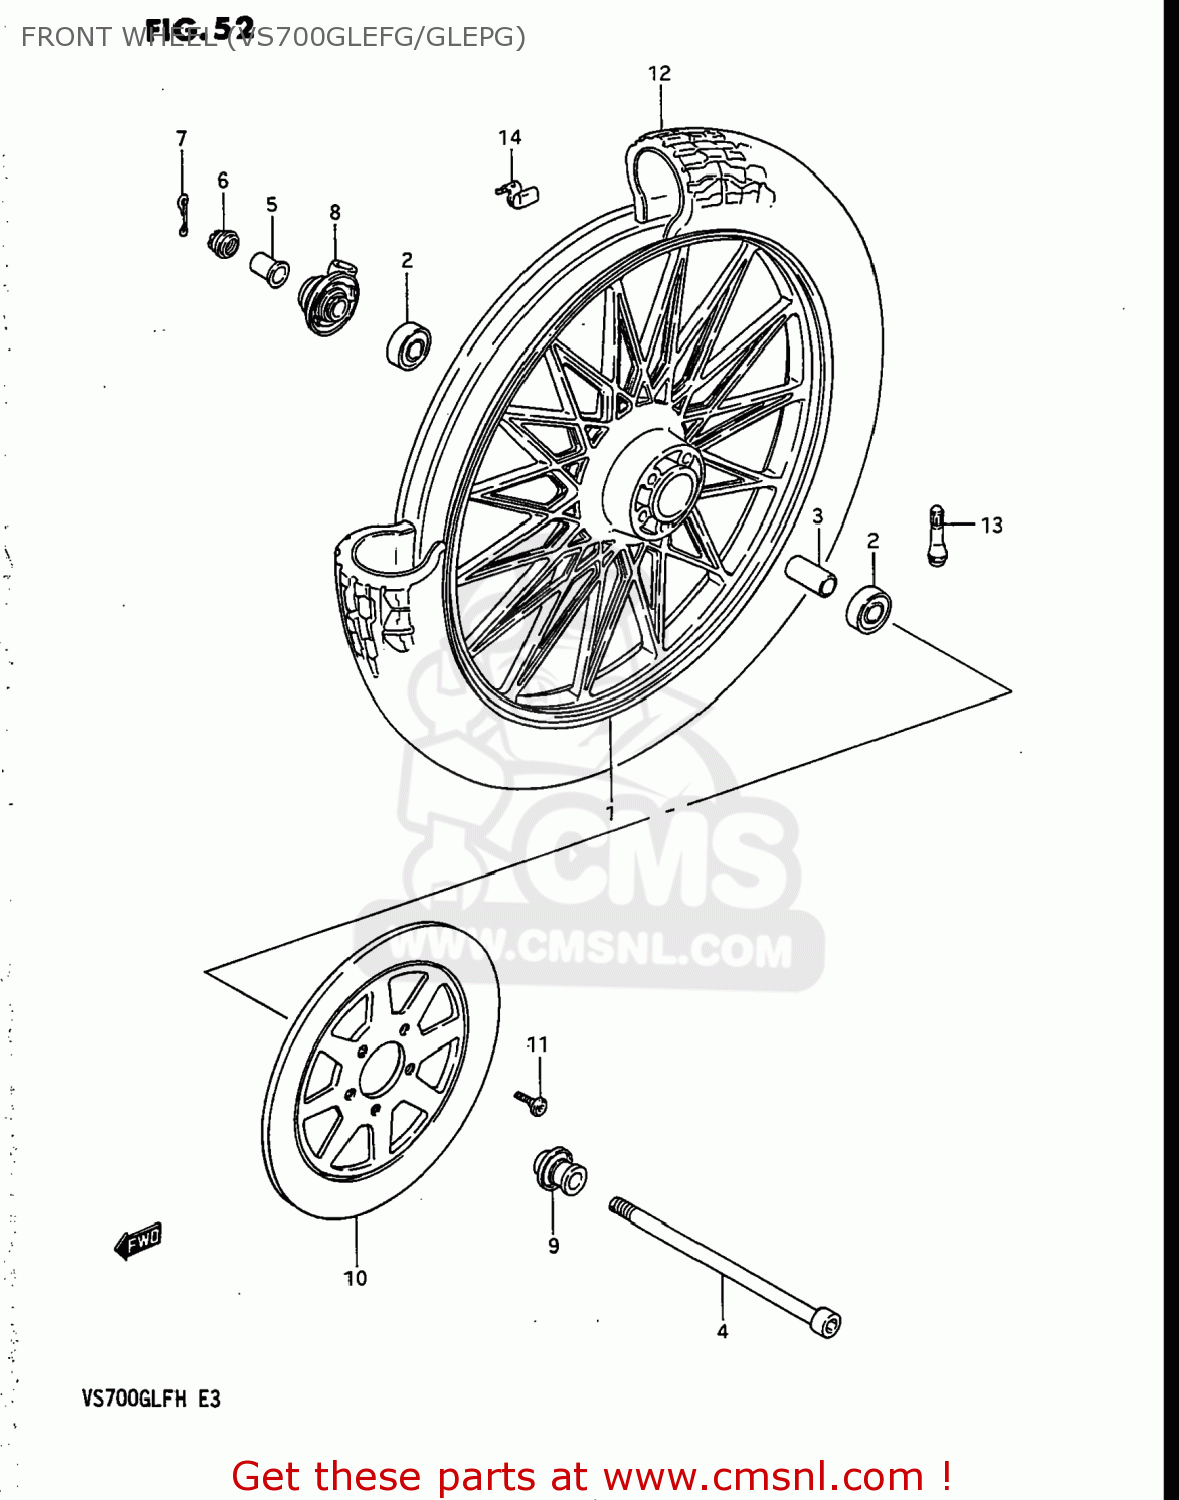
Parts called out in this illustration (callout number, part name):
1	CASTING WHEEL,FRONT 2.15-
2	BEARING
3	SPACER(15.3X21.7X65)
4	AXLE,FRONT
5	SPACER,FRONT AXLE,RIGHT
6	NUT
7	PIN,FRONT AXLE
8	BOX ASSY,SPEEDOMETER GEAR
9	SPACER COMP,FRONT AXLE
10	DISC,FRONT BRAKE
11	BOLT(8X25.5)
12	TIRE,FRONT
13	VALVE,TIRE
14	BALANCER,WHEEL
